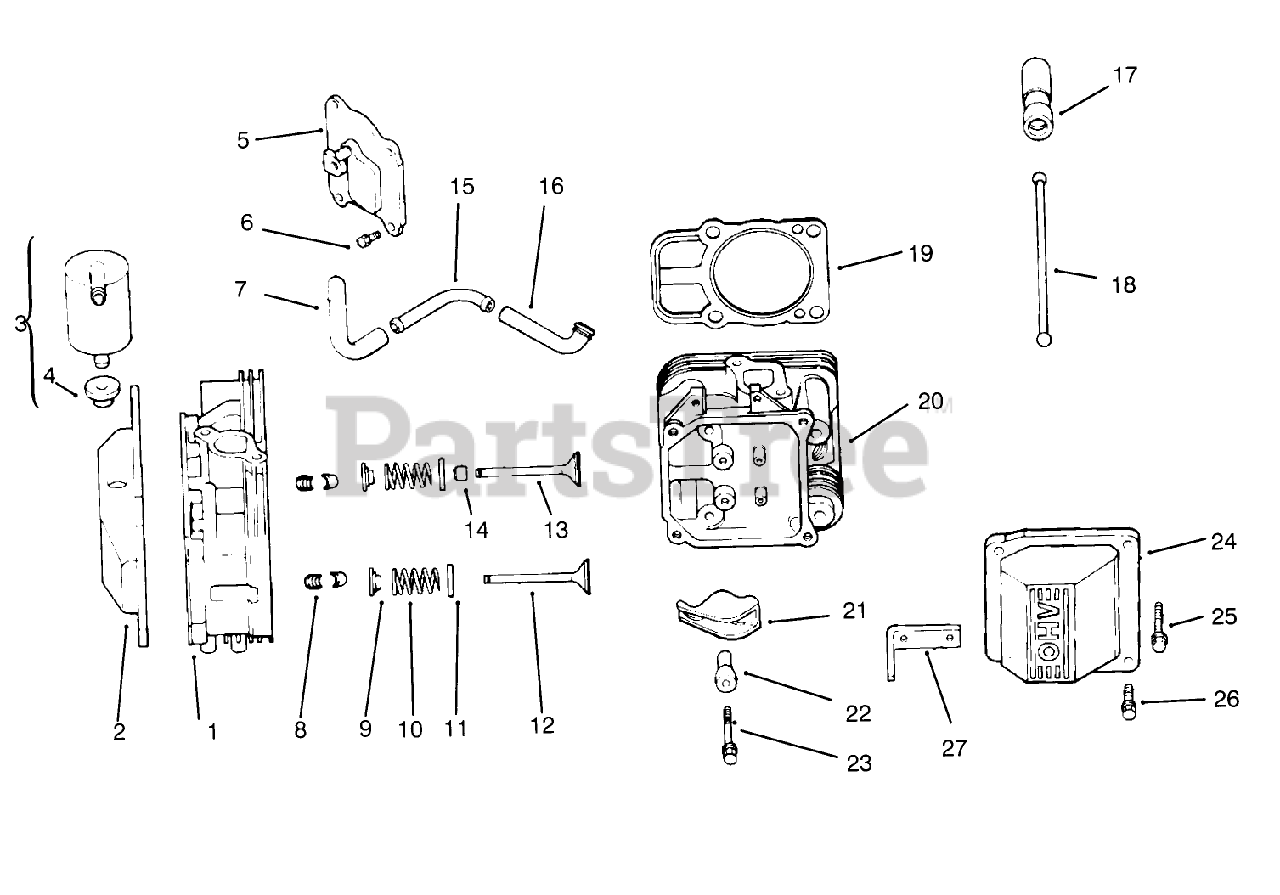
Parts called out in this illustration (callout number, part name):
1	Head ASM-#1 Cylinder (Only On: 72103, 72083)
2	Cover-Rocker (Only On: 72103)
3	Kit-Breather INCL 4 (Only On: 72103)
4	Grommet-Rubber (Only On: 72103)
5	Cover-Breather (Only On: 72103)
7	Hose-Breather (Only On: 72103)
8	Kit-Retainer
9	Cap-Valve Spring
10	Spring-Valve
11	Retainer-Spring
12	Valve-Exhaust
13	Valve-Intake
14	Seal-Valve Stem
15	Fitting (Only On: 72103)
16	Hose-Breather (Only On: 72103)
17	Lifter-Valve
18	Rod-Push (Only On: 72103,72083)
19	Gasket-Cylinder Head
20	Head ASM-#2 Cylinder (Only On: 72103, 72083)
21	Arm-Rocker (Only On: 72103,72083)
22	Ball-Rocker Pivot
24	Cover-Rocker (Only On: 72103)
25	Screw
27	Strap-Lifting
